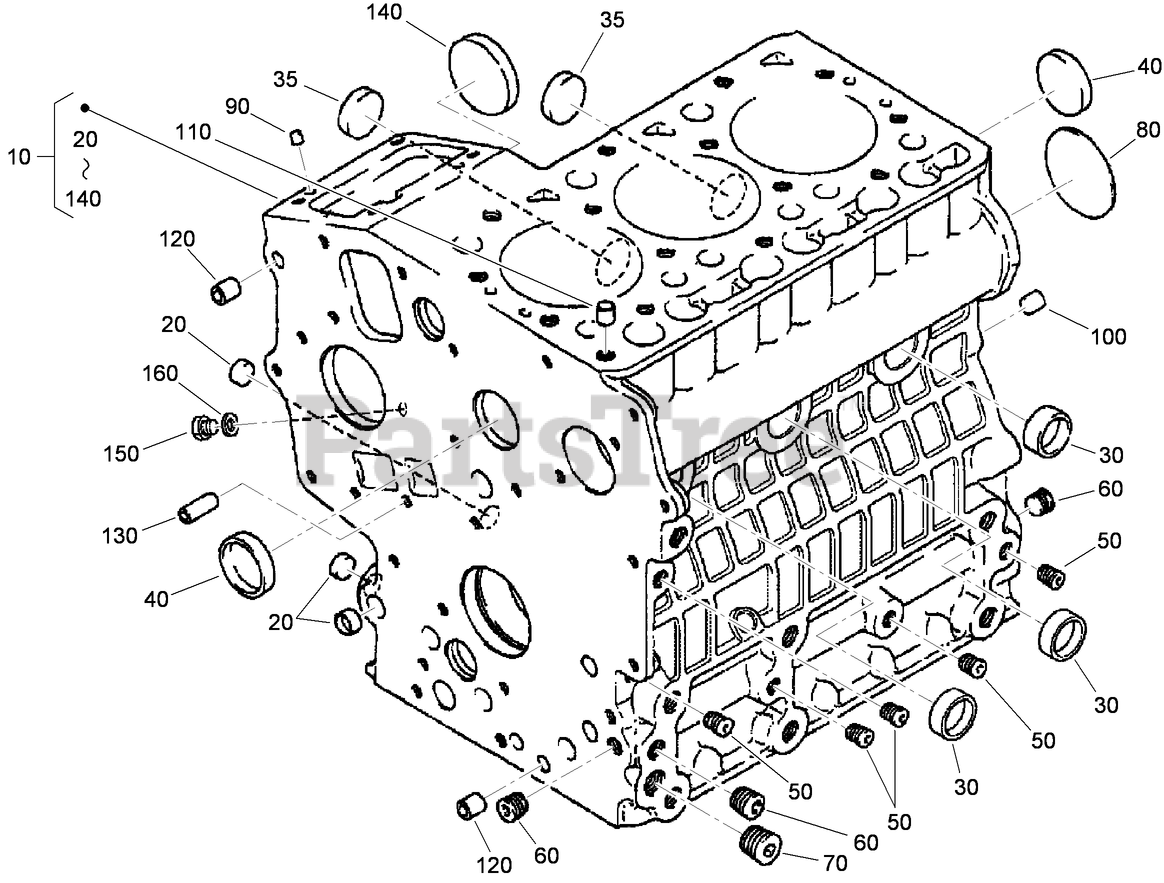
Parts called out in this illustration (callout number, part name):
10	CRANKCASE ASM
20	CAP-SEALING
30	CAP-SEALING
35	CAP-SEALING
40	CAP-SEALING
80	PLUG-EXPANSION
90	PIN-STRAIGHT
100	PIN-STRAIGHT
110	PIN-PIPE
120	PIN-PIPE
130	PIN-PIPE
140	COVER-FUEL, CAMSHAFT
160	WASHER
